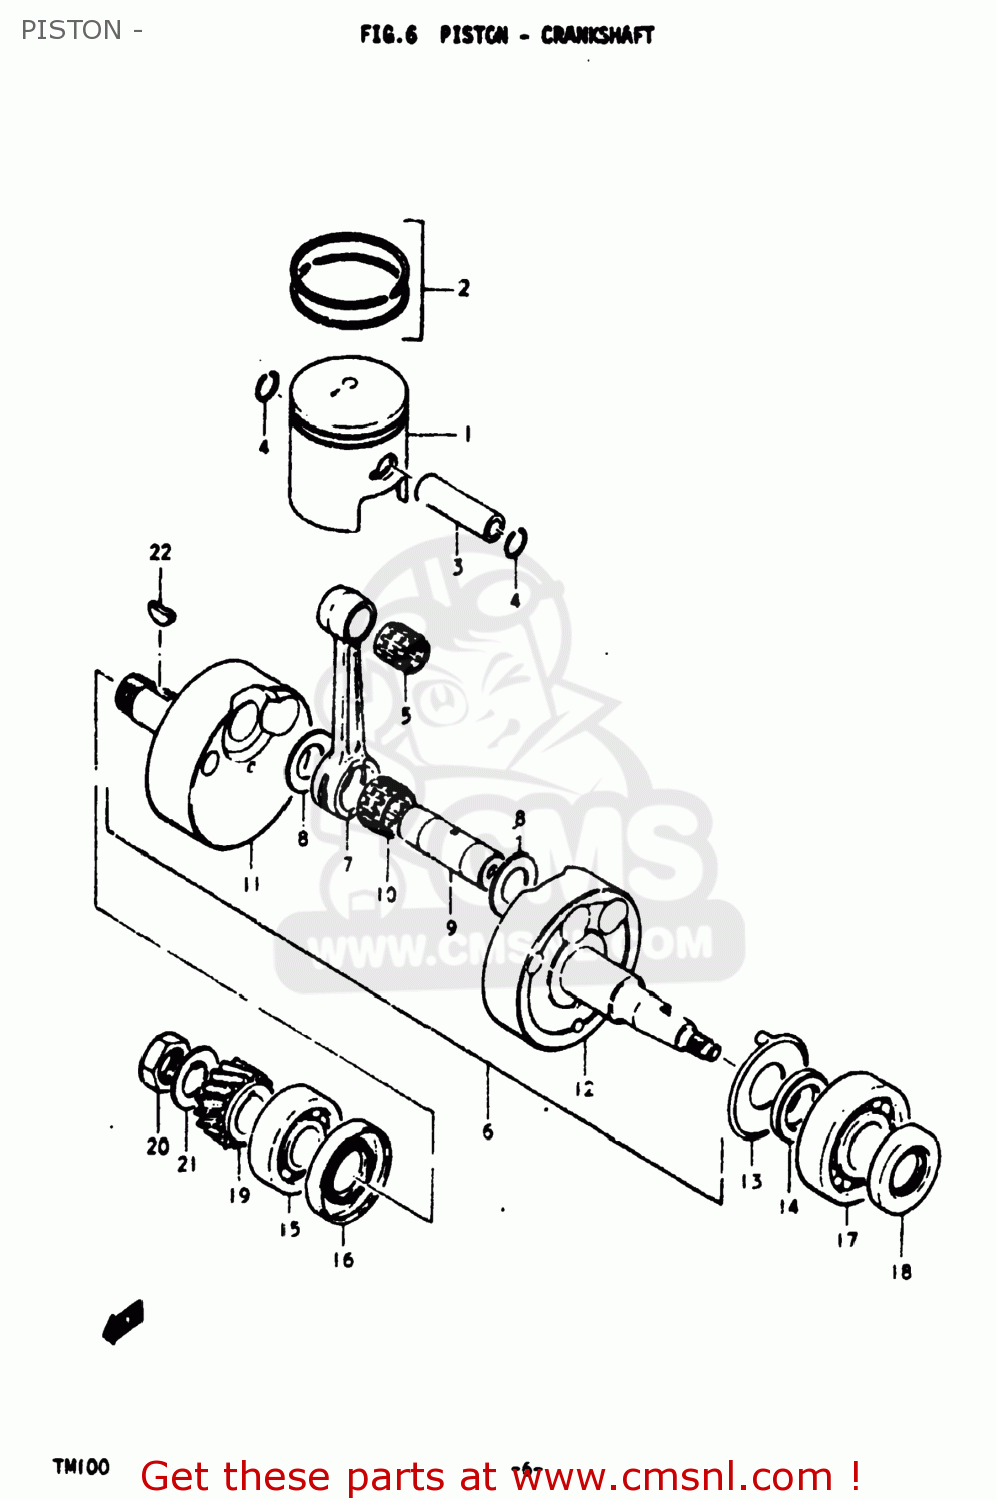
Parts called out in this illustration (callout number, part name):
1	PISTON
2	RING SET,PISTON
3	PIN,PISTON 14MM
4	RING,SNAP 14MM
5	BEARING
6	CRANKSHAFT ASSEMBLY
7	CONNECTING ROD
8	WASHER
9	PIN,CRANK
10	BEARING
11	CRANKSHAFT
12	CRANKSHAFT,LEFT
13	PLATE,CRANKSHAFT OIL GUIDE
14	SPACER
15	BEARING
16	SEAL,OIL(26X52X8)
17	BEARING(25X62X17)
18	OIL SEAL
19	GEAR,PRIMARY DRIVE
20	NUT
21	WASHER
22	KEY
